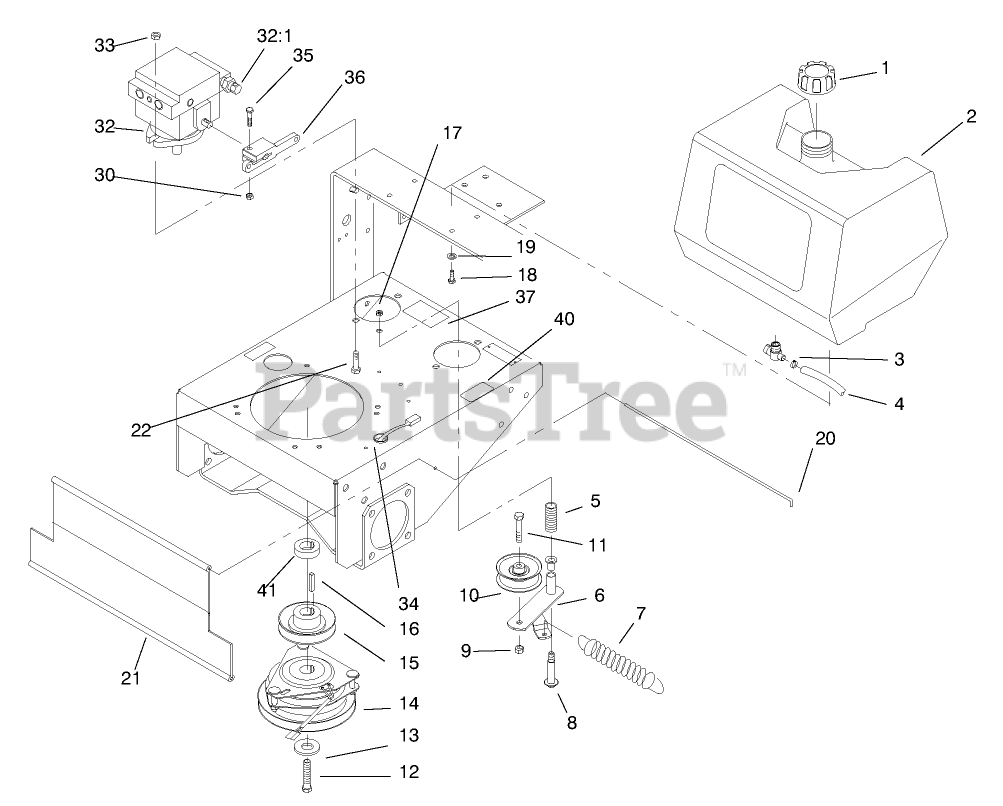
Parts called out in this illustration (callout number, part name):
1	GAS CAP ASM
2	TANK-FUEL
3	CLAMP-HOSE
4	HOSE-FUEL
5	SPRING-COMPRESSION
6	Lever-Idler
7	SPRING
8	BOLT-WHEEL
9	NUT-LOCK, NI
10	Pulley-Idler
11	SCREW-HH
12	SCREW-HH
13	WASHER
14	CLUTCH/BRAKE
15	Pulley
16	KEY-SQUARE
17	NUT-LOCK
18	SCREW-HH
19	WASHER-LOCK
20	ROD-SHIELD
21	SHIELD-TRAILING
22	SCREW-HH
30	NUT-LOCK, NI
32	HYD PUMP ASM
32:1	ASSEMBLY - VALVE
33	NUT-HF
34	GROMMET
35	SCREW-HH
36	ARM-PUMP
37	DECAL-ADJUSTMENT, VALVE
